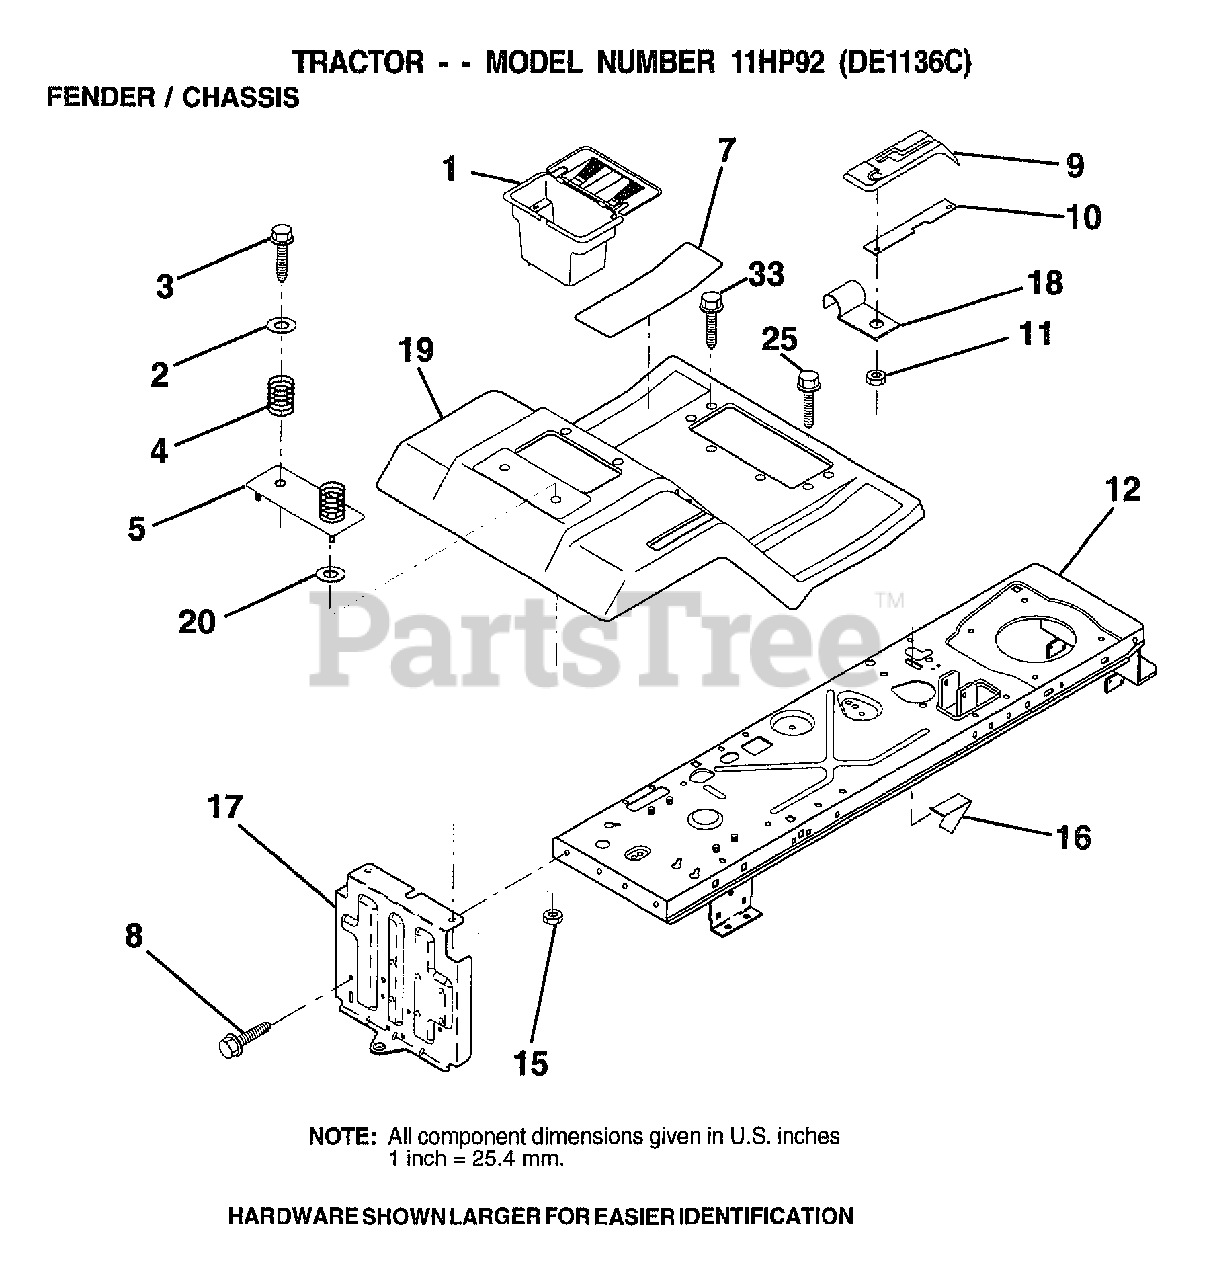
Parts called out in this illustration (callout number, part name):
1	"CASE,BATTERY.MECH"
2	WASHER
3	SCREW
4	SPRING COMPRESSIO
5	PLATE, BATTERY
7	PAD FOOTREST
8	SCREW
9	CONSOLE.SHT.4SP.
10	PLATE LOCK SHIFT
11	NUT
12	CHASSIS.WELD.ASM.
15	NUT HXKEP 1/4X20
17	DRAWBAR ASM LR
18	"CLIP,INSULATOR"
19	FENDER.FOOTREST
25	SCREW TAPPING
33	SCREW
